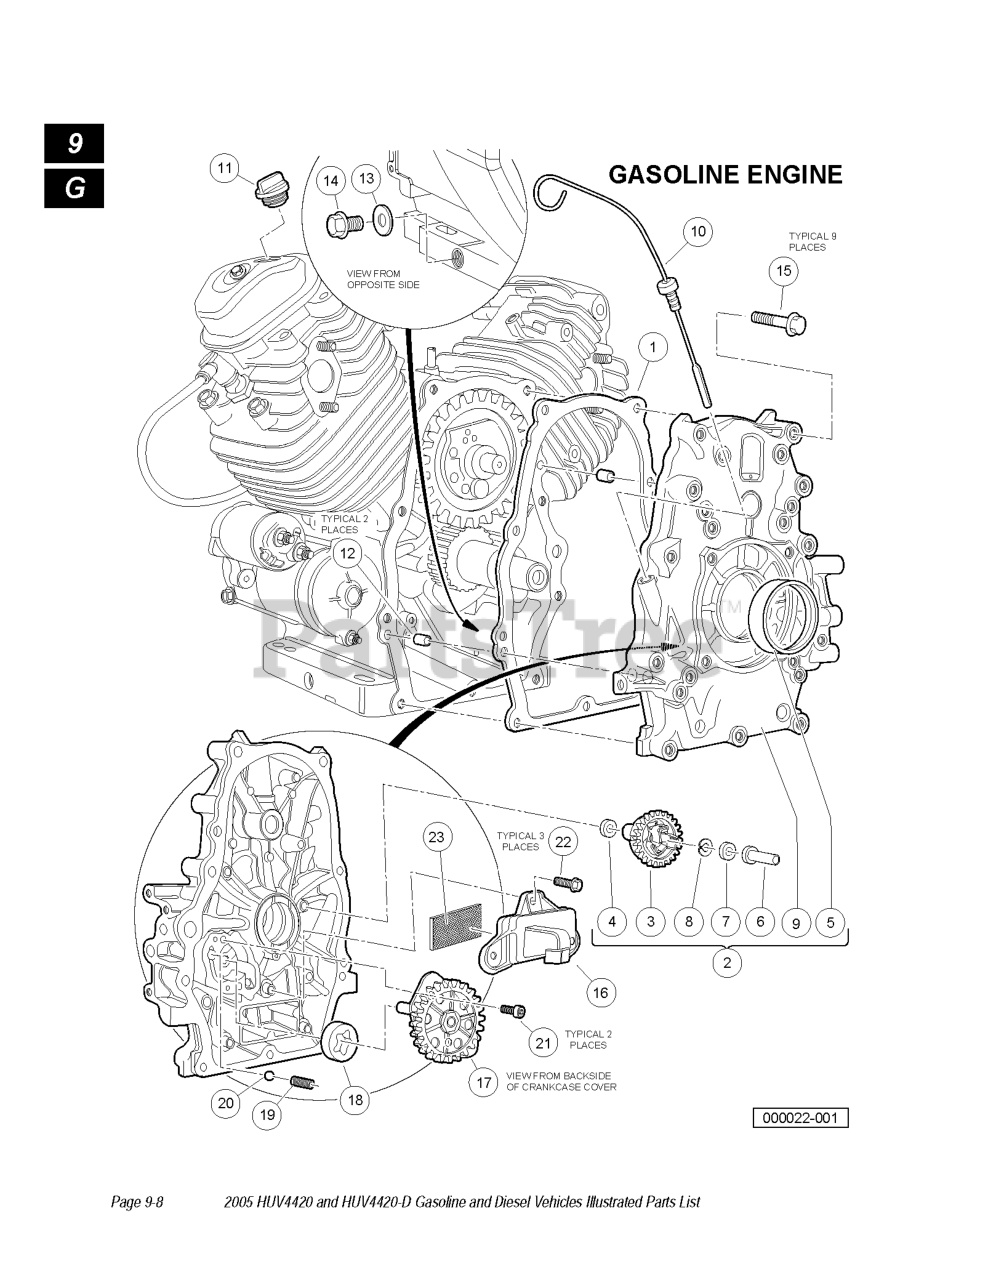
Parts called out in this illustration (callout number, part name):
1	GASKET, CASE COVER
2	COVER ASSY., CRANKCASE
3	GOVERNOR ASSY.
4	WASHER, PLAIN, M6
5	SEAL, OIL, 38 X 58 X 9
6	SLIDER, GOVERNOR
7	WASHER, 6 X 16
8	CLIP, GOVERNOR
10	DIPSTICK, OIL
11	CAP, OIL FILLER
12	PIN A, DOWEL, 8 X 14
13	WASHER, DRAIN PLUG, M14
14	BOLT, DRAIN PLUG, M14
15	BOLT, FLANGE, M8 X 1.25 X 50
16	COVER, OIL FILTER
17	COVER ASSY., OIL PUMP
18	ROTOR, OIL PUMP, OUTER
19	SPRING, RELIEF VALVE
20	BALL, STEEL, 3/8, #12
21	BOLT, SOCKET
22	BOLT, FLANGE, M6 X 1 X 20
23	SCREEN OIL FILTER
